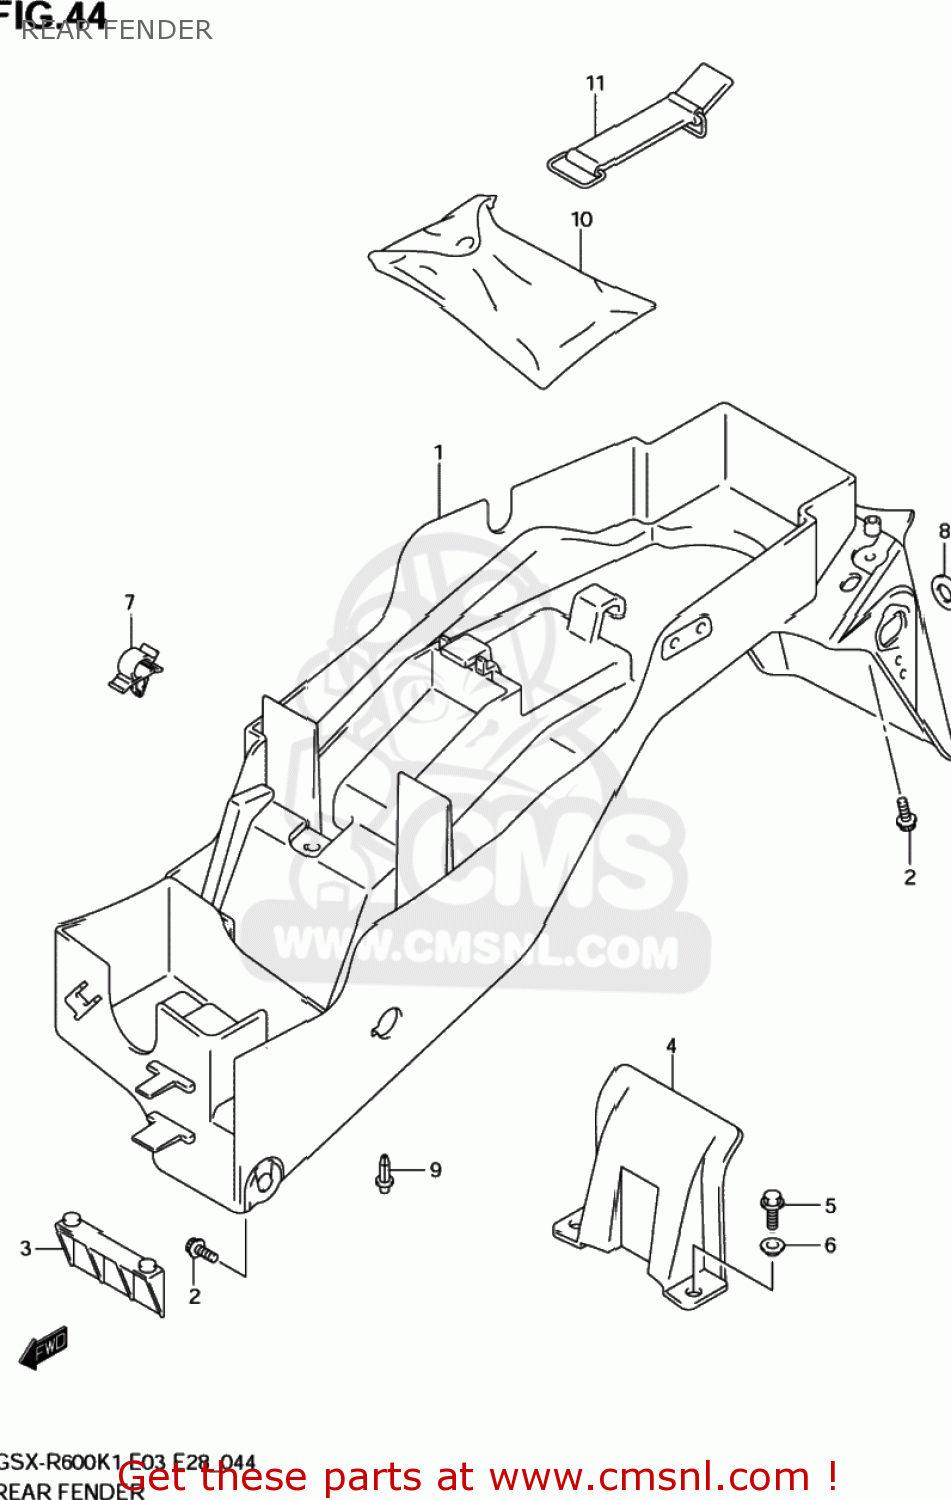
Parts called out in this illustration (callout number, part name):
1	FENDER,RR
2	BOLT(6X18)
3	MUD GUARD,REAR FENDER
4	MUDGUARD,RR FENDER LWR
5	BOLT
6	WASHER
7	CLAMP
8	WASHER(6.5X18X1)
9	CLIP(BLACK)
10	TOOL ASSY
11	BAND,TOOL
